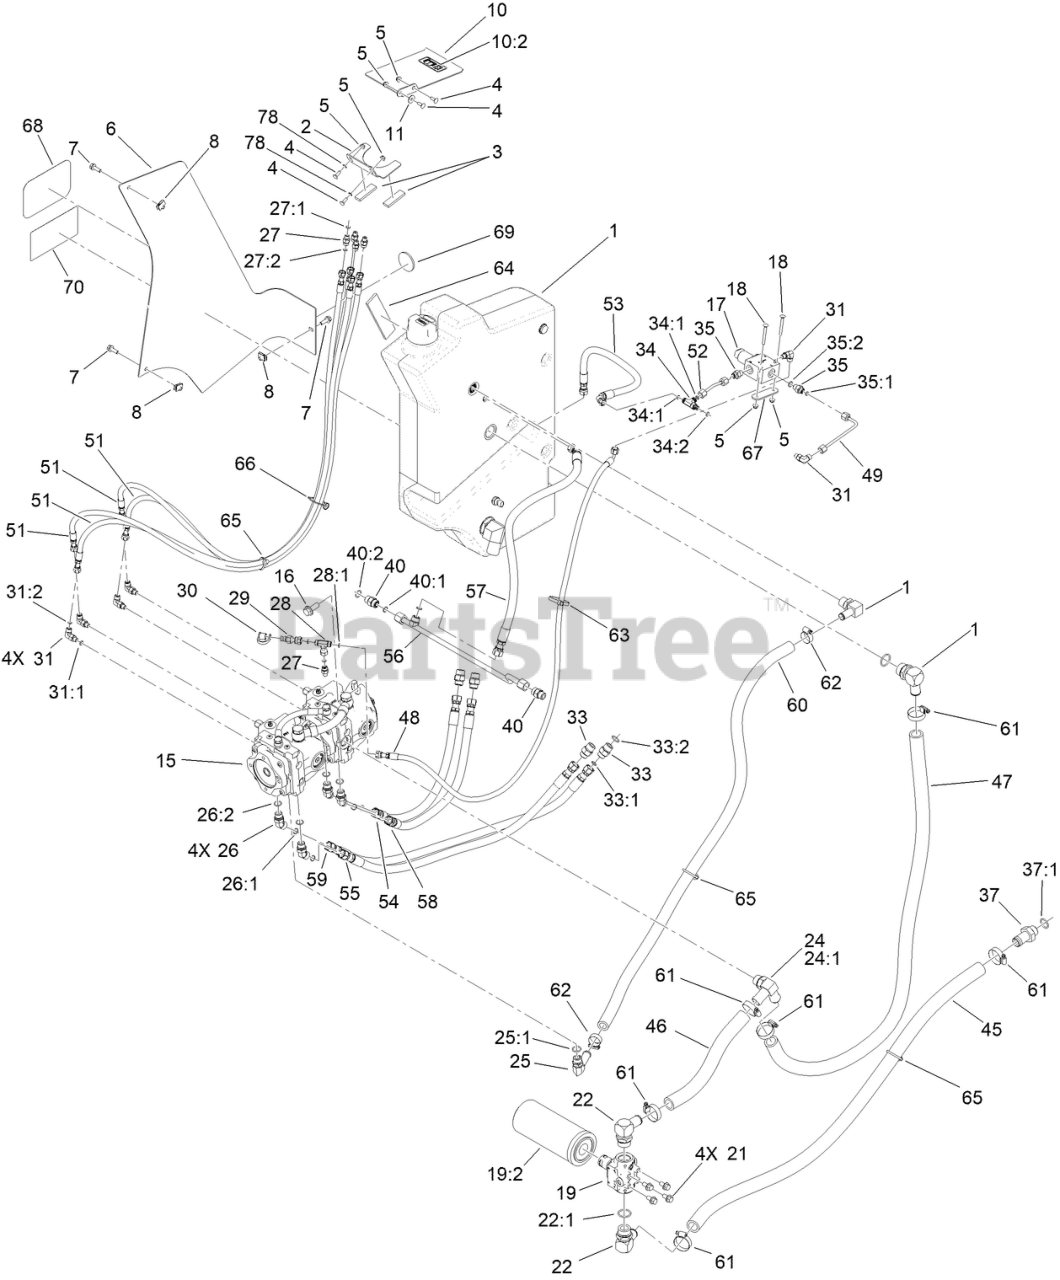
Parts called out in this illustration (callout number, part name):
1	TANK ASM-HYD
2	BRACKET-TANK, HOLD DOWN
3	PAD-FOAM
4	BOLT-CARR
5	NUT-HF
6	TANK COVER ASM-HYD
7	SCREW-HHF
8	NUT-CLIP, U
10	TANK BRACKET ASM-HYD
10:2	DECAL-HYD FLUID
11	WASHER-BELLEVILLE
15	PUMP-TANDEM
16	SCREW-HF
17	VALVE-PROPORTIONAL PRESSURE REDUCING
18	SCREW-CARR
19	FILTER HEAD ASM
19:2	ELEMENT-FILTER
21	SCREW-HHF
22	STEM-BARB-90
22:1	O-RING
24	CONNECTOR
24:1	O-RING
25	FITTING-90
25:1	O-RING
26	FITTING-HYD, 45 DEG
26:1	O-RING
26:2	O-RING
27	FITTING-STRAIGHT
27:1	O-RING
27:2	O-RING
28	FITTING-TEE
28:1	O-RING
29	NIPPLE-TEST
30	CAP-DUST, RUBBER
31	FITTING-ELBOW, 90 DEG
31:1	O-RING
31:2	O-RING
33	FITTING-STRAIGHT
33:1	O-RING
33:2	O-RING
34	FITTING-TEE
34:1	O-RING
34:2	O-RING
35	FITTING-STRAIGHT
35:1	O-RING
35:2	O-RING
37	FITTING
37:1	O-RING
40	FITTING-STRAIGHT
40:1	O-RING
40:2	O-RING
45	HYD HOSE
46	HYD HOSE
47	HYD HOSE
48	HYD HOSE ASM
49	HYD TUBE ASM
51	HYD HOSE ASM
52	HYD TUBE ASM
53	HYD HOSE ASM
54	HYD HOSE ASM
55	HYD HOSE ASM
56	HYD TUBE ASM
57	HYD HOSE ASM
58	HYD HOSE ASM
59	HYD HOSE ASM
60	HYD HOSE
62	CLAMP-HOSE
63	TIE-CABLE
64	PAD-RUBBER
65	CLIP-TIE
66	MOUNT-TIE WRAP, MAGNETIC
67	BRACKET-CLAMP, VALVE
68	DECAL-TORO LOGO
69	REFLECTOR-RED
70	DECAL-TX1000 TURBO
78	NUT-RETAINING
